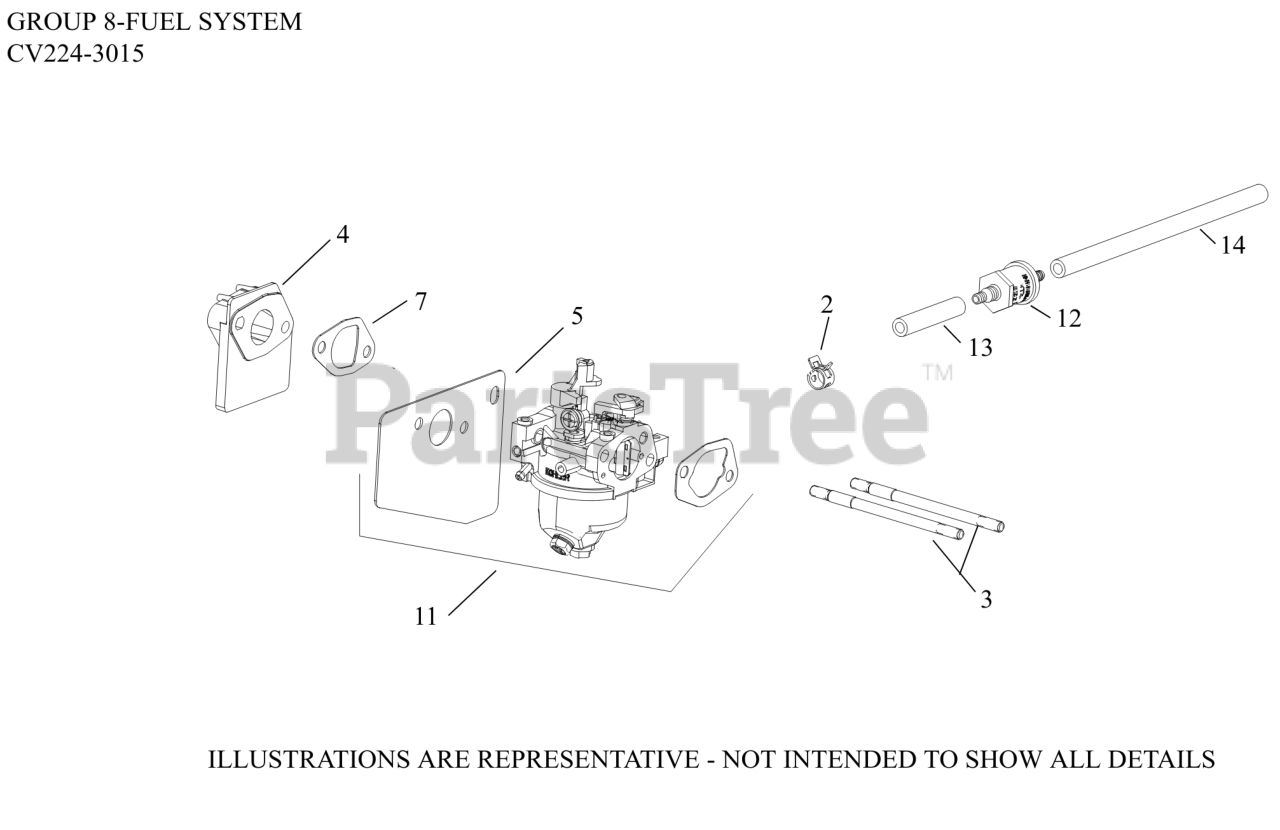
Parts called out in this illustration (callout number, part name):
2	CLAMP, HOSE (NON-CALIF)(#1423710S)
3	STUD,M6X1.0X100.2MM
4	KIT, SPACER
5	KIT, CARBURETOR HEAT SHIELD GASKET
7	KIT, INTAKE GASKET
11	KIT, CARBURETOR COMPLETE
12	FILTER, FUEL
13	HOSE, FUEL LOW-PERMEATION
14	HOSE, FUEL LOW-PERMEATION
NI	KIT,HIGH AL(4000-8000 FT)USE 14 755 04-S
NI	KIT, CARBURETOR REPAIR (RUIXING)
